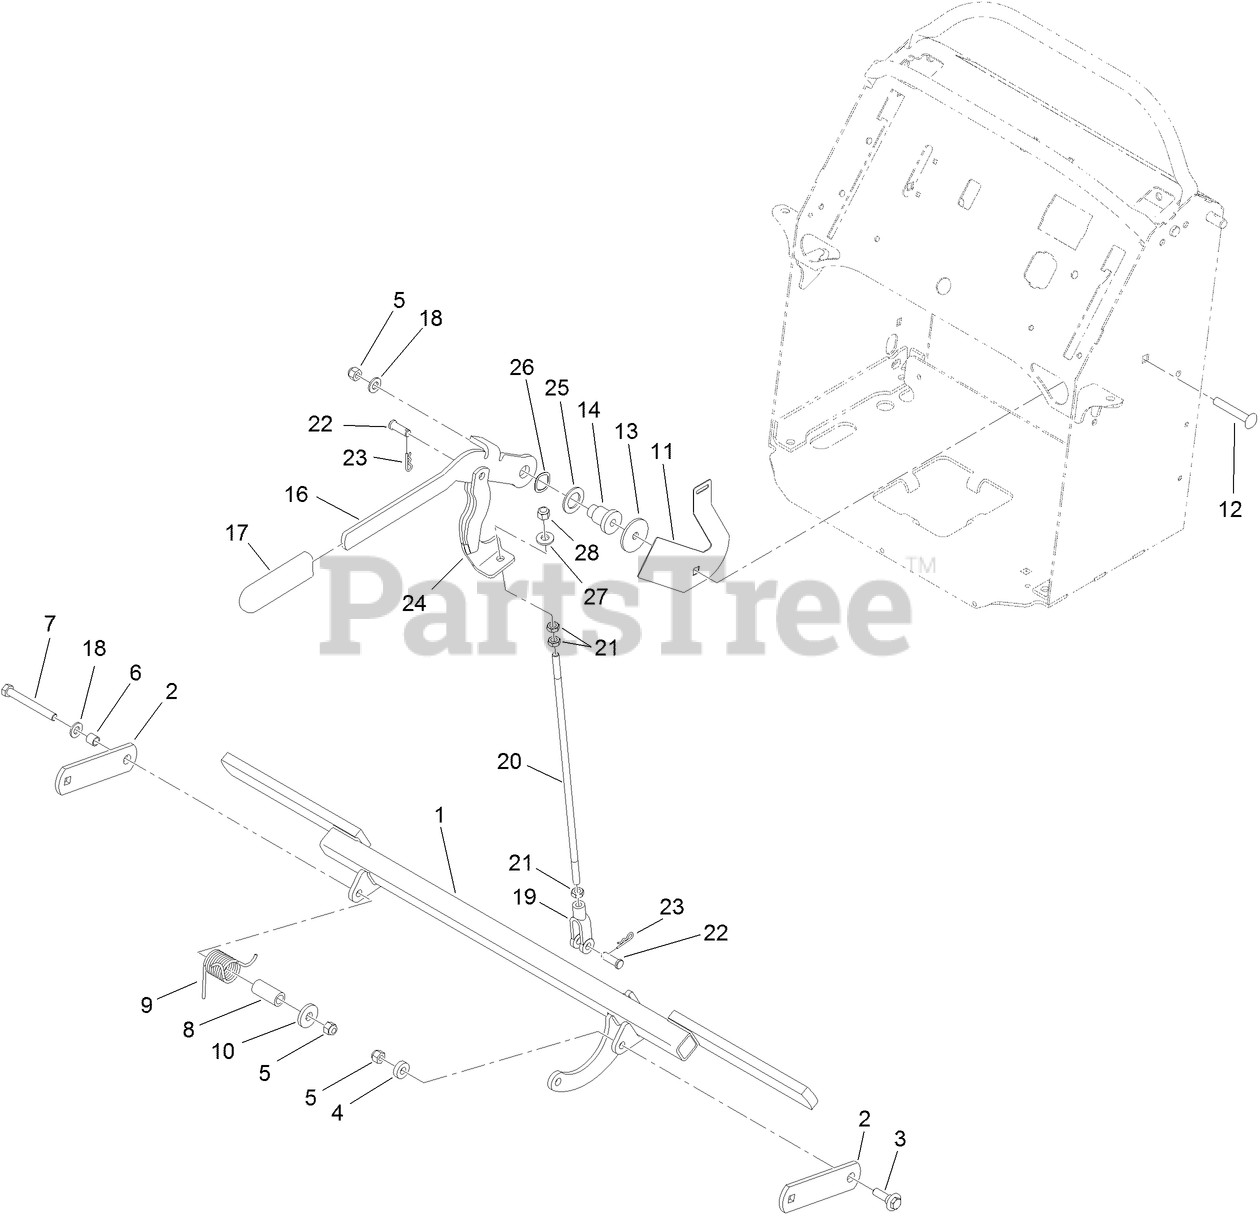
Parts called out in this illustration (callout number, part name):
1	BAR-BRAKE
2	SUPPORT-BRAKE
3	SCREW-SHOULDER, HWH
4	SPACER
5	NUT-HF, NI
6	SPACER
7	SCREW-HH
8	SPACER
9	SPRING-TORSION
10	WASHER
11	PLATE-SWITCH, BRAKE
12	SCREW-CARR
13	WASHER-REBOUND
14	MOUNT-PULLEY
16	LEVER-BRAKE
17	GRIP-LEVER
18	WASHER-FLAT
19	YOKE-LINKAGE, BRAKE
20	ROD-BRAKE
21	NUT-HJ
22	PIN-CLEVIS
23	PIN-COTTER
24	ARM-BRAKE
25	WASHER
26	Washer-Wave
27	WASHER-BELLEVILLE
28	NUT-LOCK
